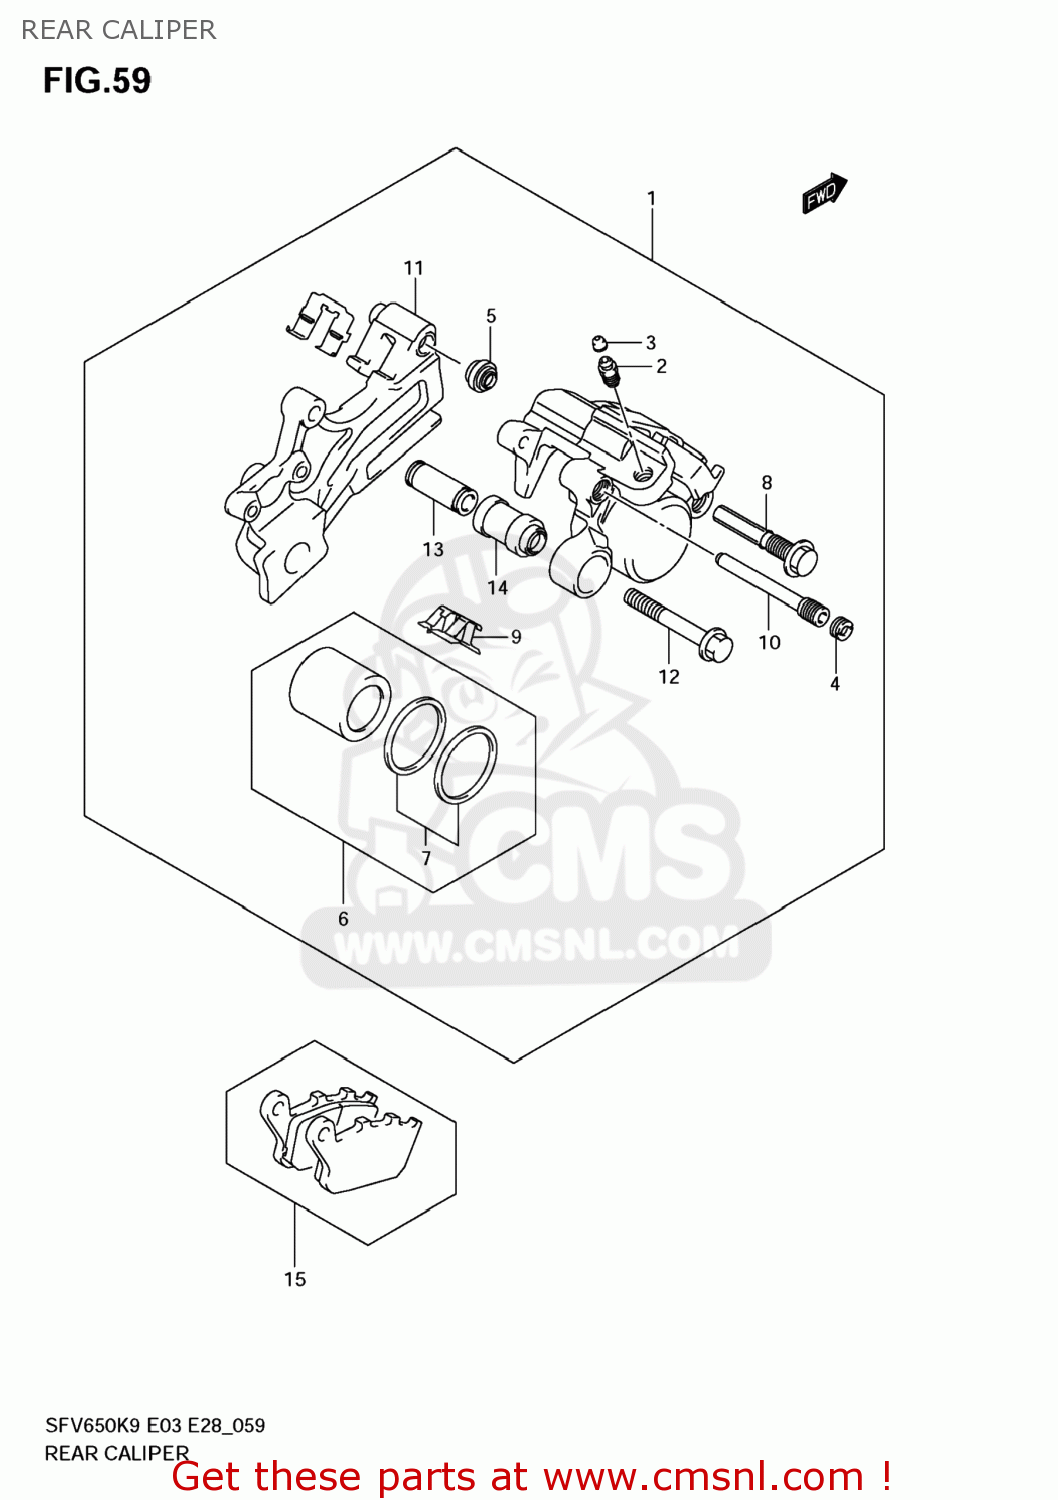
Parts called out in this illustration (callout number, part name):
1	CALIPER ASSY,RR
2	BLEEDER
3	CAP,BLEEDER
4	PLUG,PIN
5	BOOT
6	PISTON SET
7	SEAL SET,PISTON
8	BOLT
9	SPRING,PAD
10	PIN,PAD
11	BRACKET
12	BOLT
13	SLEEVE
14	BOOT,SLEEVE
15	PAD SET (NAS)
